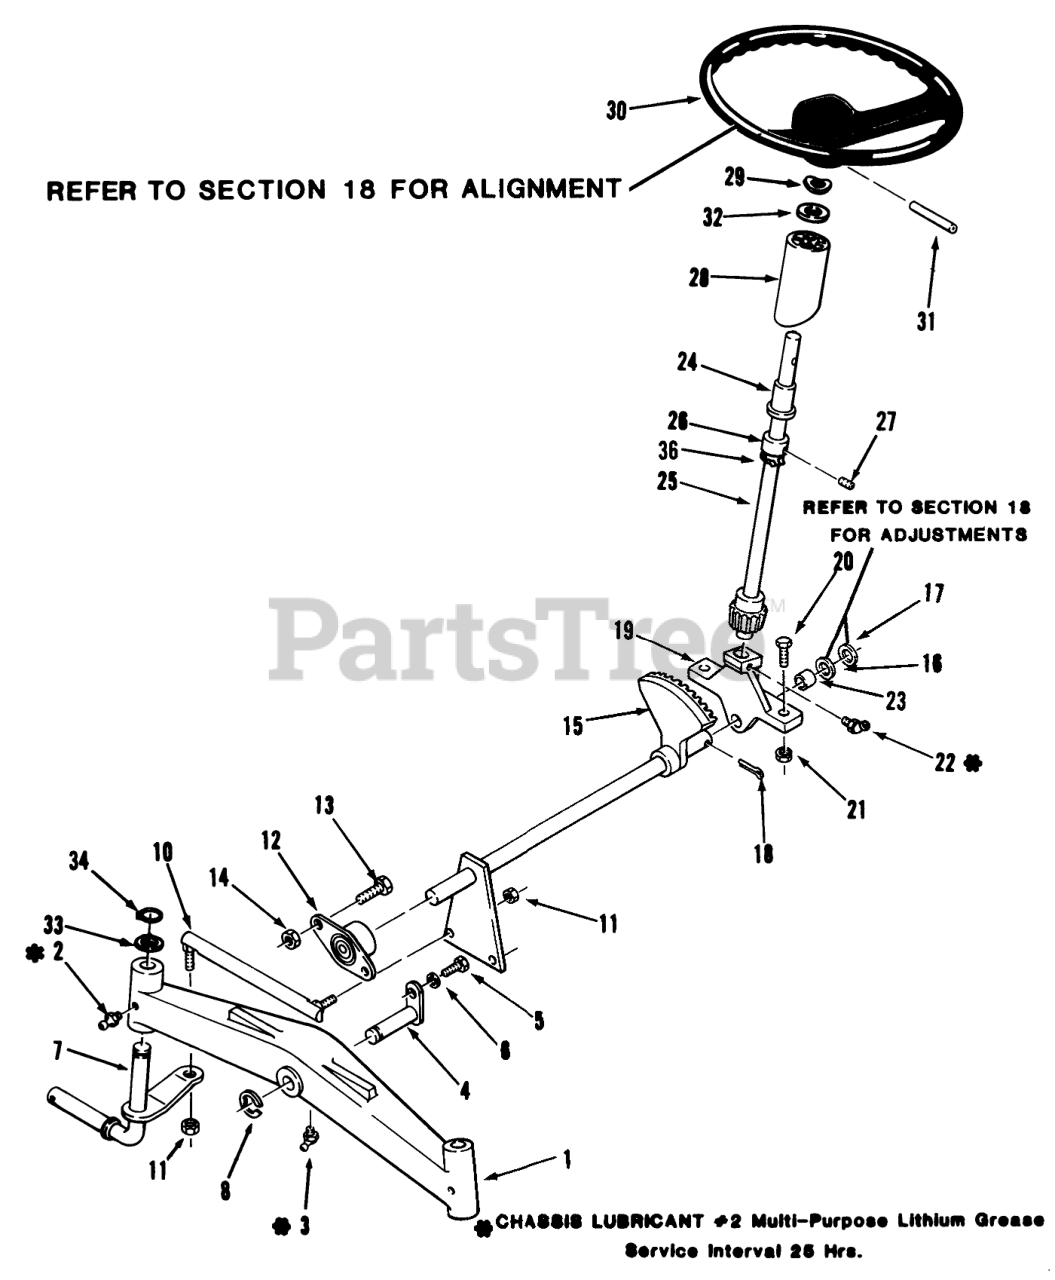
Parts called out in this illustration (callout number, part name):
3	FITTING-GREASE
4	PIN AND PLATE ASM
8	E-RING
12	BEARING-FLANGED
16	WASHER-SHIM
17	WASHER
22	FITTING-GREASE
23	BEARING-BRONZE
24	BEARING-FLANGED
28	TUBE-STEERING
29	WASHER-BOWED
32	WASHER-FLAT
33	WASHER
36	RING-RETAINING
